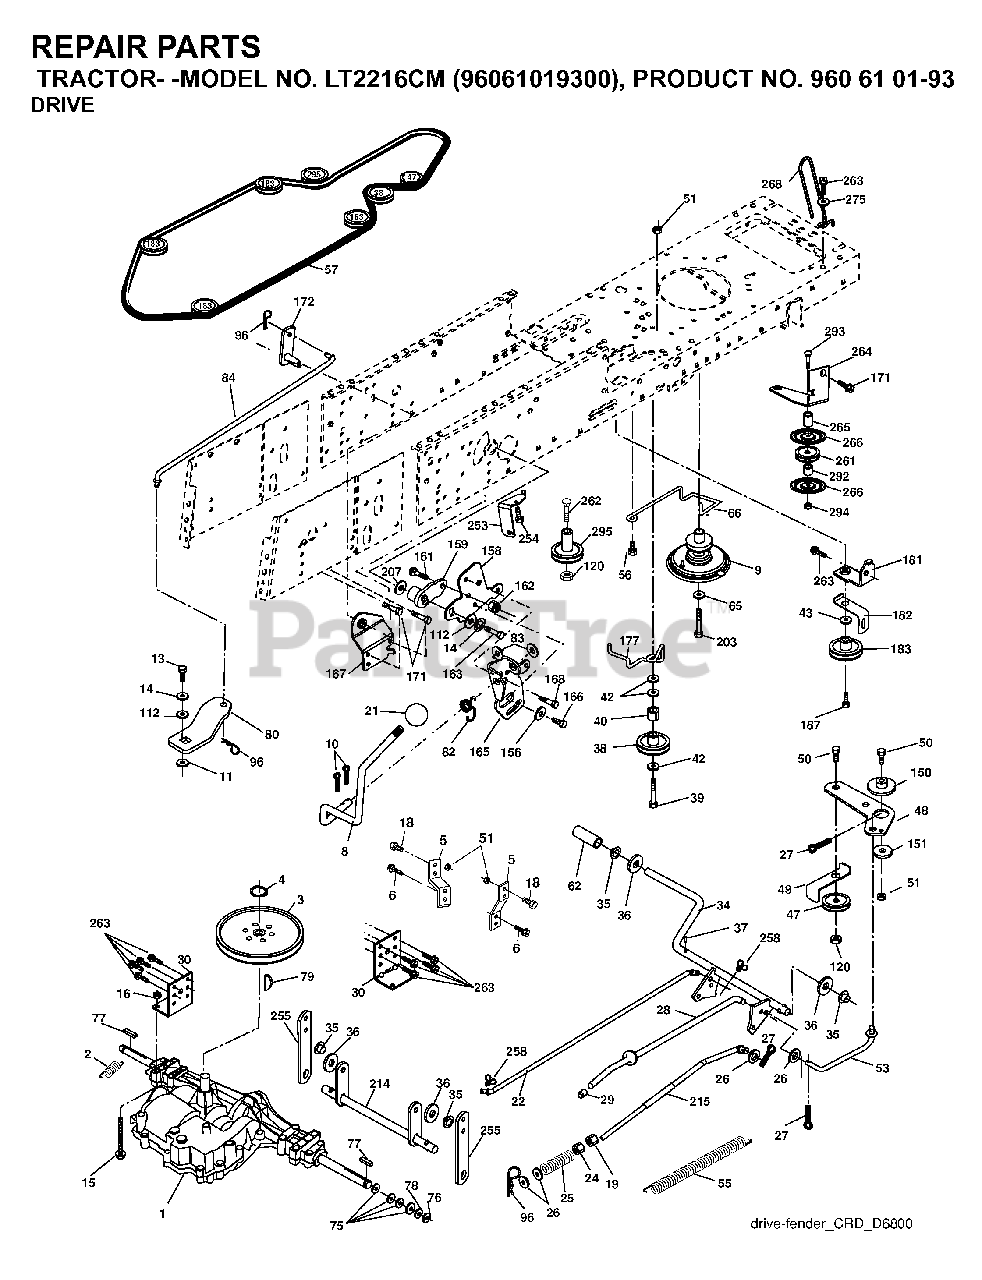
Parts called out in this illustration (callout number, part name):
2	SPRING,BRAKE RETURN
4	RETAINING RING LT
5	STRAP TORQUE
6	SCREW 5/16"
8	ROD SHIFT FENDER ADJUST LT
10	PIN COTTER
11	WASH-SHFT PLT LT
13	BOLT 1/4-28X3/4
14	LOCKWASHER
15	BOLT HEX 5/16-18 GR 5
16	NUT.71038.31-18.HEX.NYLOCK
19	NUT
21	KNOB.DUCKHEAD.1/2
24	NUT
25	SPRING ROD LT
27	COTTER PIN
28	ROD, PARKING BRAKE
29	PLUNGER CAP
30	BRKT, MOUNT TRNSAXLE
34	SHAFT, FOOT PEDAL
35	BEARING.NYLON
36	WASHER LT
37	DRIVE PIN
38	PULLEY.FLAT
42	WASHER
47	IDLER PULLEY
48	BELLCRANK, CLUTCH
49	RETAIN BELT
50	BOLT.3/8-16X1.50
51	LOCKNUT
53	LINK.CLUTCH.7.66.2005
55	SPRING, RETURN LT
56	SCREW.3/8-16
62	PEDAL COVER T
65	LOCKWASHER
66	KEEPER BELT ENGINE
76	E-RING LT
77	SQUARE KEY
80	ARM SHIFT
82	SHIFT SPRING
83	WASHER
96	RETAINER M
112	WASHER LT
120	NUT LOCK FLG 3/8-16 UNC
150	BUSHING.BELLCRANK.GRD.DR
151	WASHER 12/32X2X10GA
156	WASHER.SRRTD.5/16
158	BRACKET
159	HUB.SHIFT
161	BOLT
162	NUT.CROWNLOCK.1/4
165	RP BRACKET
167	BRACKET
168	BOLT.SHOULDER.5/16-18X
187	BOLT.5/16-18X1.25
207	WASHER NYL
254	SCREW 3/8-16X1
258	CLIP RETAINER
261	FLAT IDLER PULLEY
263	SCREW, 3/8-16X3/4
275	WASHER
294	NUT, HEX 3/8-16
295	PULLEY IDLER COMPOSITE
